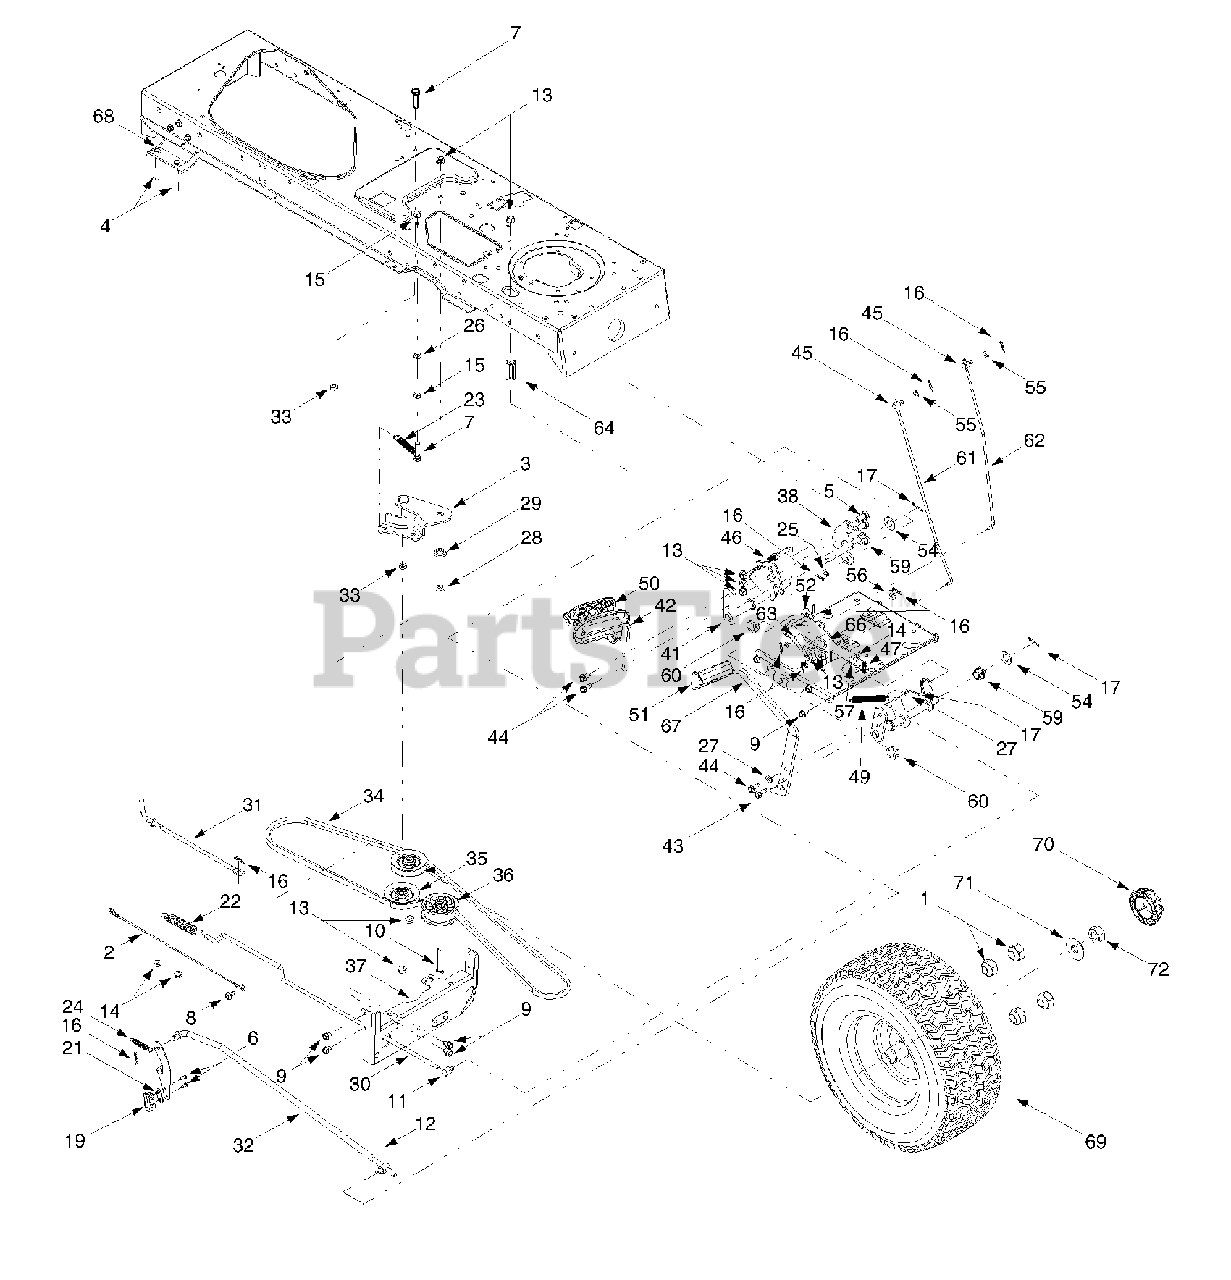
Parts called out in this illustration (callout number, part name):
1	Lug Nut, 3/4-16
2	Reverse/Ground Wire Harness Adapt
3	Double Idler Bracket Assembly
4	Hex Cap Screw, 5/16-18 x 3.00
5	Hex Cap Screw, 3/8-16 x .75
6	Screw, #8-18 x .5
7	Hex Cap Screw, 3/8-16 x 1.5
8	Self-tapping Screw, 1/4-20 x .50
9	Self-tapping Screw, 5/16-18 x .625
10	Hex Cap Screw, 3/8-16 x 2.25
11	Ferrule, 5/16-18
12	Ferrule, 3/8-24
13	Flange Lock Nut, 3/8-16
14	Flange Lock Nut, 5/16-18
15	Hex Nut, 3/8-16
16	Internal Cotter Pin
17	Cotter Pin
18	Cable Tie
19	Short Spring Switch
20	Push-mount Cable Tie
21	Insulator Nut Plate
22	Extension Spring, .59 x 4.0
23	Extension Spring, .5 x 3.5
24	Extension Spring, 3/8 x 1.44
25	Flat Washer, .385 x .62 x .063
26	Lock Washer, 3/8
27	Flat Washer, .344 x .688 x .065
28	Flat Washer, .407 x .812 x .135
29	Shoulder Spacer, .38
30	Hydrostatic Control Rod
31	Hydrostatic Bypass Rod
32	Hydrostatic Brake Rod
33	Spacer, .376 x .625 x .22
34	Drive Belt
35	V-idler Pulley, 3.06
36	Flat Idler Pulley, 2.75
41	Drive Control Assembly
42	Hydro Pedal Assembly
43	Self-tapping Screw, 5/16-18 x .875
44	Self-tapping Screw, 5/16-18 x .75
45	Ferrule, 1/4-20
46	Pin, 3/8-16 x 2.43
47	Compression Spring, .40 OD x 1.17
48	Extension Spring, .50 OD x 1.41
49	Extension Spring, .50 OD x 6.37
50	Drive Pedal Pad
51	Brake Pedal Pad
52	Flat Washer, .411 x 1.25 x 1.0
53	Flat Washer, .281 x .50 x .063
54	Flat Washer, .64 x 1.24 x .06
55	Flat Washer, .344 x .062 x .03
56	Flat Washer, .406 x .875 x .105
57	Shoulder Screw, .437 x 1.62
58	Shoulder Screw, .5 x .434
59	Hex Flange Bearing
60	Split Hex Flange Bearing
61	Cruise Control Rod
62	Brake Lock Control Rod
63	Cruise Latch
64	Spacer, 5/16 x 1.54
66	Drive Lockout Bracket
70	Hub Cap
71	Flat Washer, .780 x 1.59 x .062
72	Jam Nut, 3/4-16
